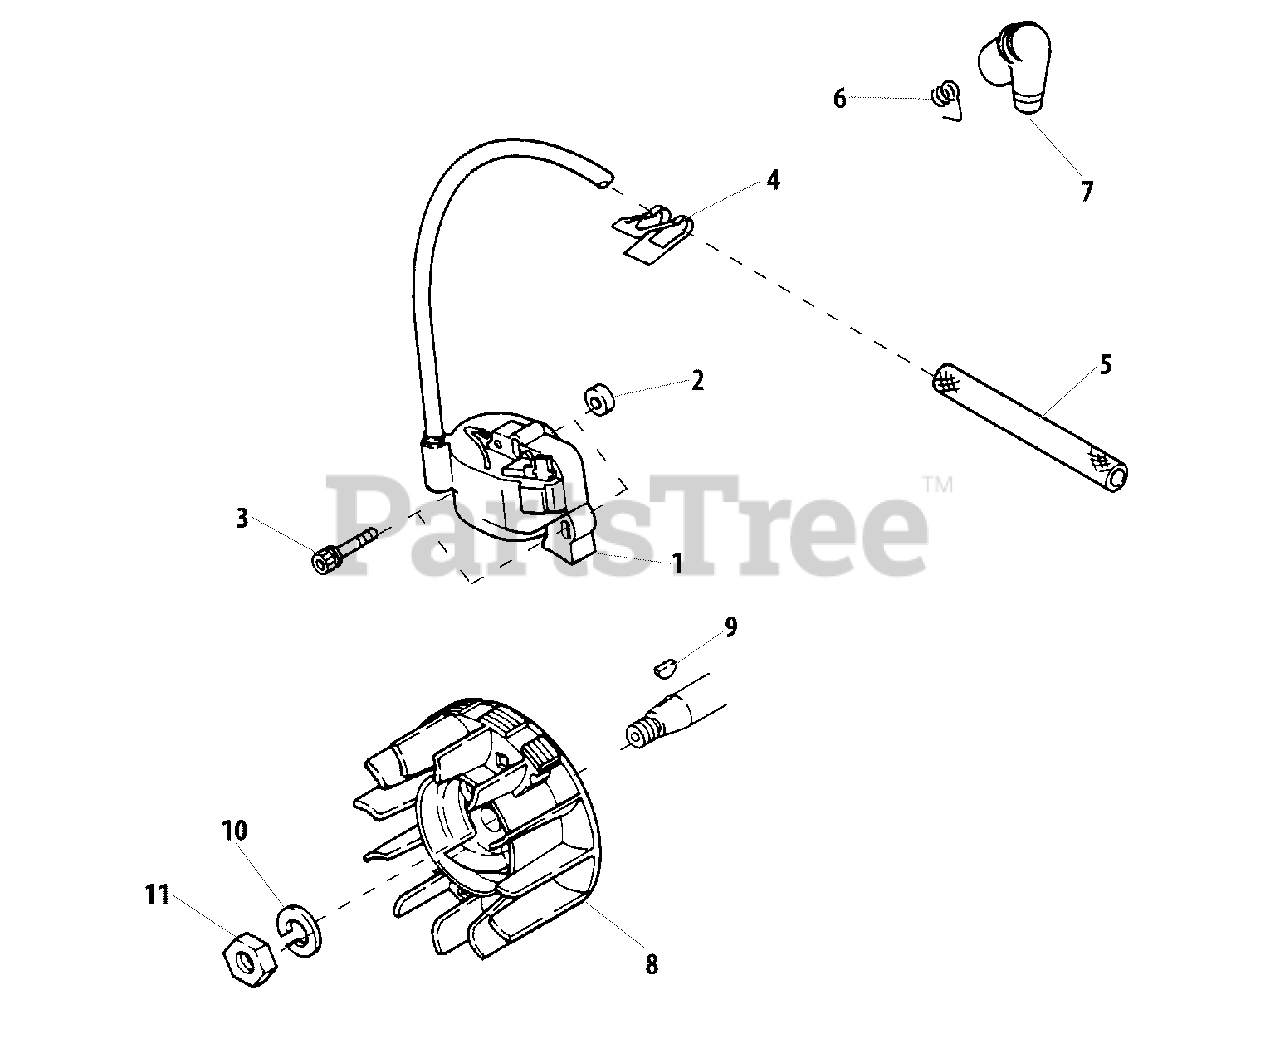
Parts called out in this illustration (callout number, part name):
1	COIL, IGNITION
2	INSULATOR
4	CLIP
5	TUBE
6	TERMINAL, SPARK PLUG CAP
7	CAP, SPARK PLUG
8	FLYWHEEL
9	KEY - 3X10
10	LOCKWASHER - 8
11	NUT
